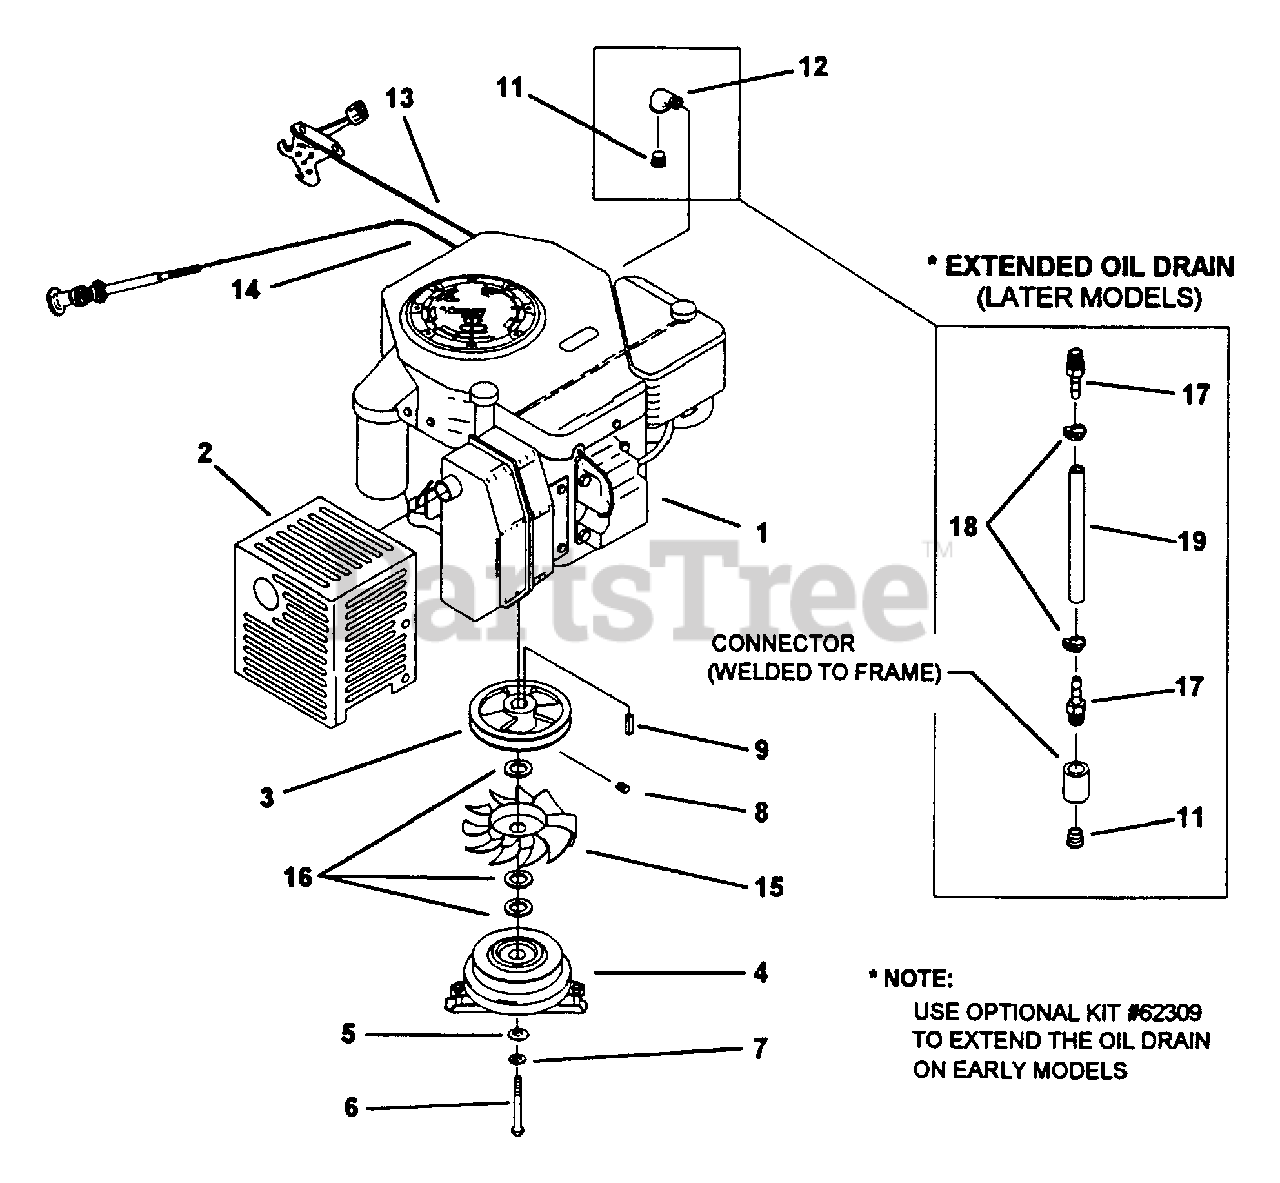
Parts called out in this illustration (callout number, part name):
1	ENGINE, 14 HP KOHLER COMMAND
2	MUFFLER GUARD WELDMENT, KOHLER
3	PULLEY, MOTOR DRIVE
4	CLUTCH, ELECTRIC, 1" BORE
5	WASHER, 15/32" I.D.
6	CAPSCREW, HEX HD. 10M-1.5 X 90MM
7	LOCKWASHER, 7/16" SPLIT SPRING
8	SETSCREW, SOCKET HD. 5/16-18 X 3/8"
9	KEY, 1/4" SQ. X 1"
11	PLUG, PIPE 3/8"
12	ELBOW, STREET, 3/8" 90D. SCH. 40
13	CABLE, THROTTLE 12HP & 14HP
14	CABLE, CHOKE 12HP & 14HP
15	FAN, 7" DIA. 10 BLADE CW
16	WASHER, SHIM
17	HOSE BARB, 3/8" HOSE X 3/8" MPT
18	HOSE CLAMP, 19/32-21/32, NYLON
19	HOSE, 8" LONG
